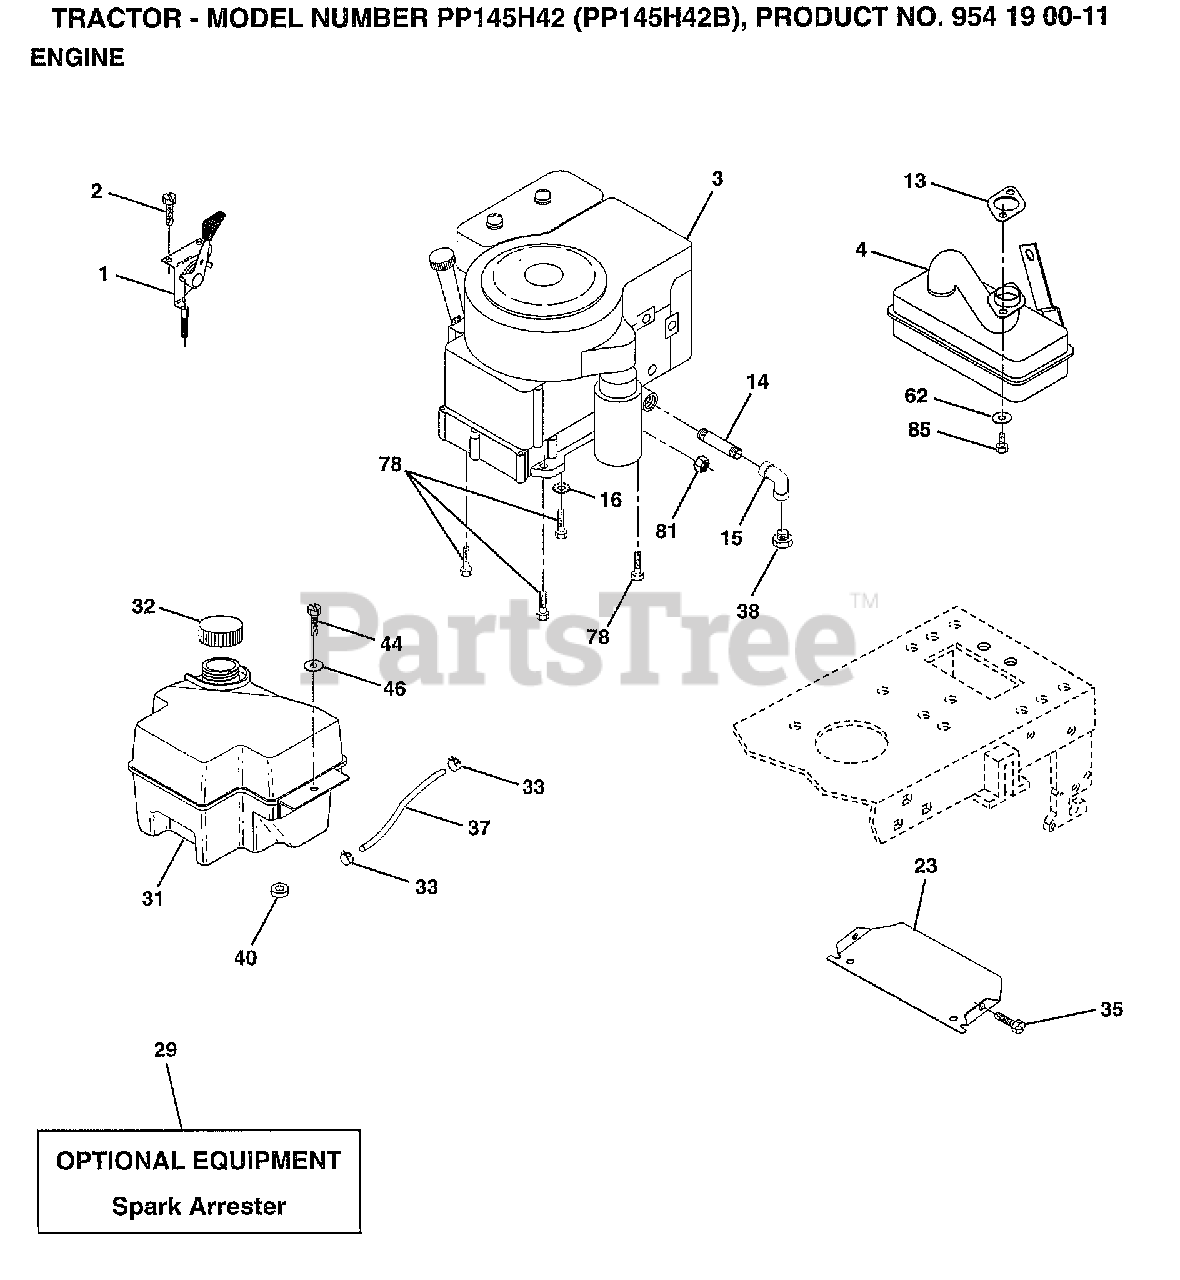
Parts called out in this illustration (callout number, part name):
1	CONTROL.THTL.23.5
2	SCREW LT
4	MUFFLER
13	GASKET MUFFLE TEC
14	PIPE NIPPLE LT
15	ELBOW
16	LOCKWASHER
23	SHIELD-HEAT
32	CAP ASM FUEL
33	HOSE CLAMP
35	SCREW
37	LINE FUEL
44	SCREW HEX CRT
46	WASHER
49	SCREW GTV
62	LOCKWASHER
78	SCREW
81	NUT
85	SCREW HEX HD CAP
